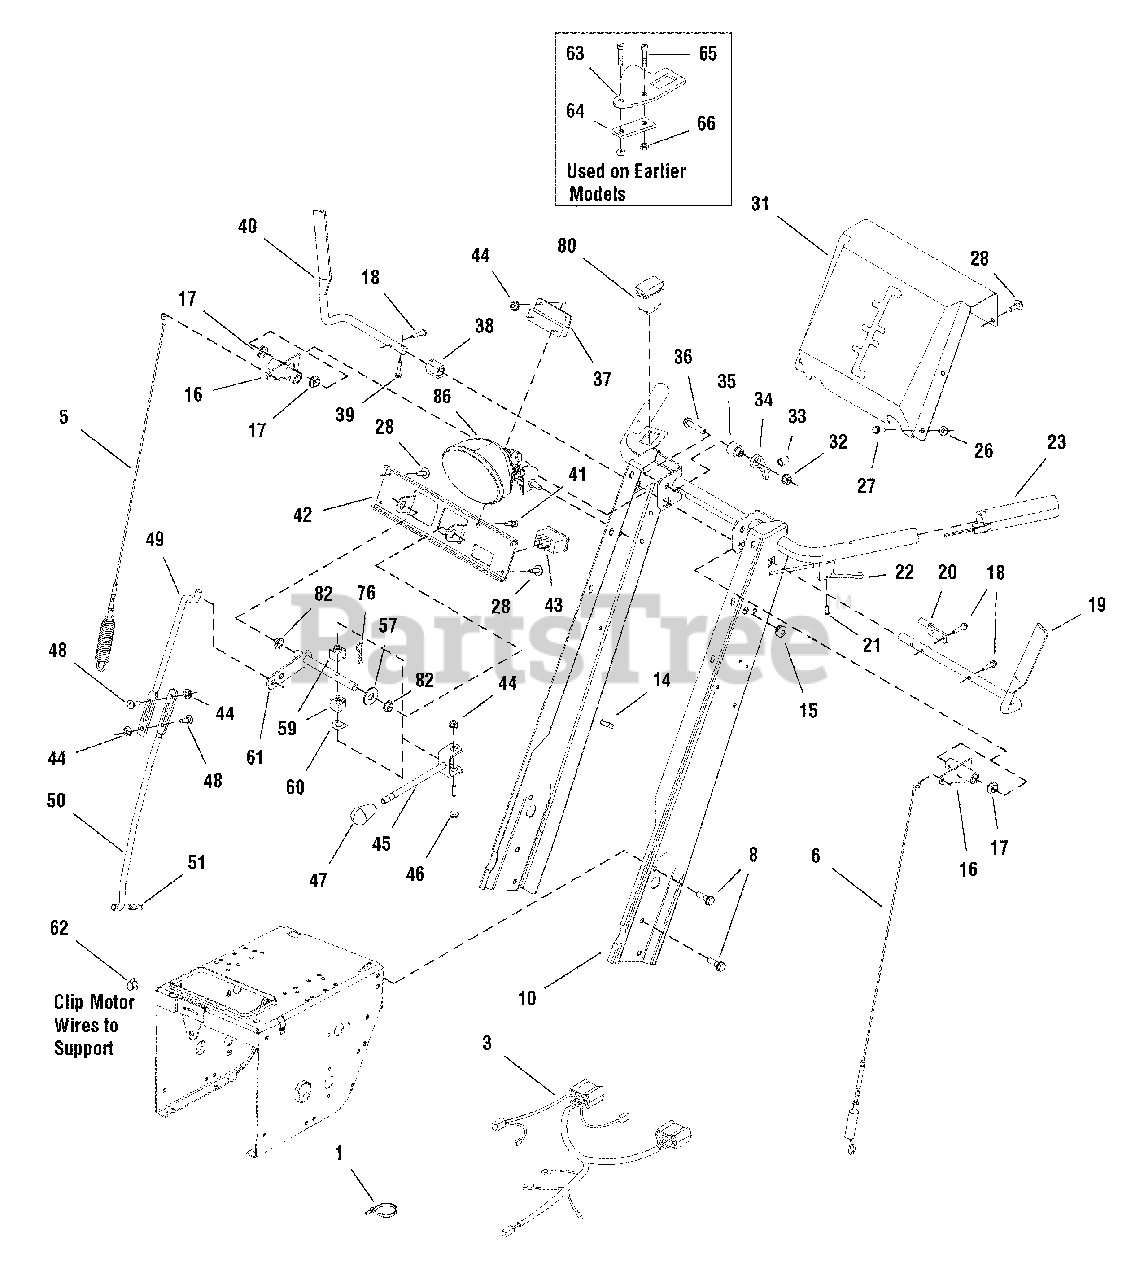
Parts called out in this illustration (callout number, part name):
1	TIE, Self Locking .184 Wide 7.31 Long
3	HARNESS, Hand Warmers/Spout
5	CABLE & SPRING ASSEMBLY, R.H. Auger
6	CABLE & SPRING ASSEMBLY, L.H. Traction
8	SCREW, Hex Head SER Flange Taptite, R5/16-18 x 1
10	HANDLE ASSEMBLY, Channel
14	CLIP, Speed Wire
15	GROMMET, 1/2 Diameter
16	LEVER & TUBE ASSEMBLY, Clutch
17	BUSHING, .52 ID x .585 Square x .22 Long Nylon
18	SCREW, Hex Washer Head Taptite, #12-24 x 1
19	HANDLE, Clutch L.H.
20	ROD, Control, 3/8 Diameter, 2.81 Long 2" Flat
21	SCREW, Pan Head Torx #10 x 1/2 Thick
22	CABLE & HANDLE ASSEMBLY
23	HAND GRIP, Heated
26	NUT, Hex Whiz Lock Flange, 1/4-20
27	CAPSCREW, Hex Washer Head, 1/4-20 x 3/4, G5
28	SCREW, Hex Washer Head Taptite, 1/4-20 x 3/4
32	NUT, Hex Flange 5/16-18 ESNA
33	SPRING, Compression, .38 ID x 1 Long
34	LATCH, Control, Powdered Metal
35	SPACER, .328 ID x .81 OD x .94 Long 1/2
36	SCREW, Hex Whiz Lock Flange, 5/16-18 x 1-1/2
37	RESISTOR BLOCK, 1.53
38	GUIDE, Control, .434 Wide 1.08 Long, Powdered Metal
39	SCREW, Hex Washer Head Taptite #10-24 x 1
40	HANDLE, Clutch R.H.
41	CAPSCREW, Hex Head 1/4-20 x 3/4, G5
42	BRACKET, Shift Control
43	SWITCH, Hand Warmer
44	NUT, Hex Keps, 1/4-20 Conical Washer
45	ROD & CLEVIS ASSEMBLY, Shift
46	SCREW, Hex Whiz Lock Flange, 1/4-20 x 2-1/4
47	KNOB, Hole, .357 Diameter 1.14 Diameter, Sphere Softer
48	CARRIAGE BOLT, 1/4-20 x 3/4, G5
49	ROD, 3/8 Diameter, 11.38 Long
50	ROD, Shift Lower
51	PIN, Quick
57	WASHER, 0500 .53 ID x 1-1/4 x .08 Thick
59	BLOCK, Pivot
60	WASHER, Curved, .525 ID x .98 OD x .014 Thick
61	ROD & ARM ASSEMBLY, Pivot,
62	CLIP, .115/.135 Panel
63	BRACKET, Switch Top
64	BRACKET, Switch Mounting Plate
65	SCREW, Truss Head Phillips
66	NUT, Hex Lock 10-24 w/Nylon
76	CLIP, Hair Pin
80	SWITCH, Chute Rotator
82	BUSHING, 1/2 ID x 3/4 OD x 1/4 Long Nylon
86	HEADLIGHT ASSEMBLY, Oval Amber
